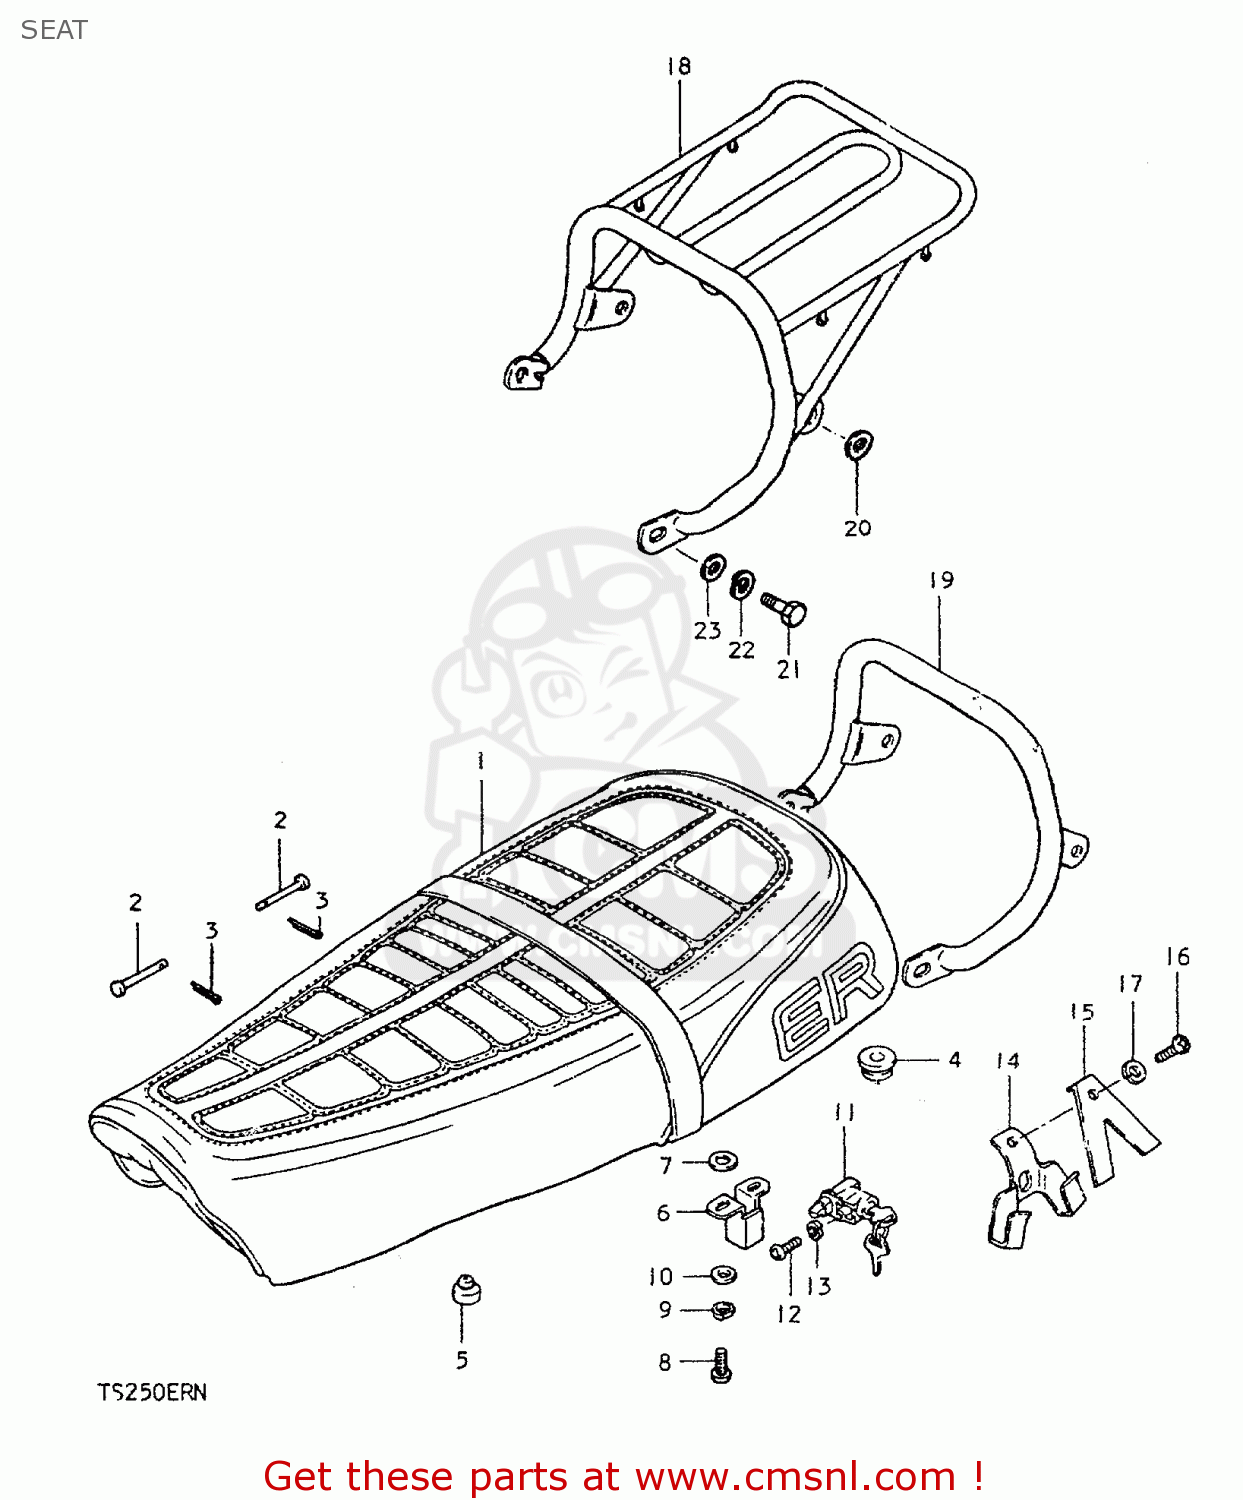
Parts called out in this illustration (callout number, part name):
1	SEAT ASSY
2	PIN
3	PIN
4	CUSHION
5	CUSHION(11.5X22X20)
6	PLATE,CLAMP GUIDE
7	WASHER(8.5X18X1)
8	SCREW 6X12
9	LOCK WASHER
10	WASHER
11	LOCK ASSY,SEAT
12	SCREW
13	LOCK WASHER
14	HOLDER,HELMET
15	SPRING OPT
16	SCREW 6X12
17	LOCK WASHER
18	CARRIER
